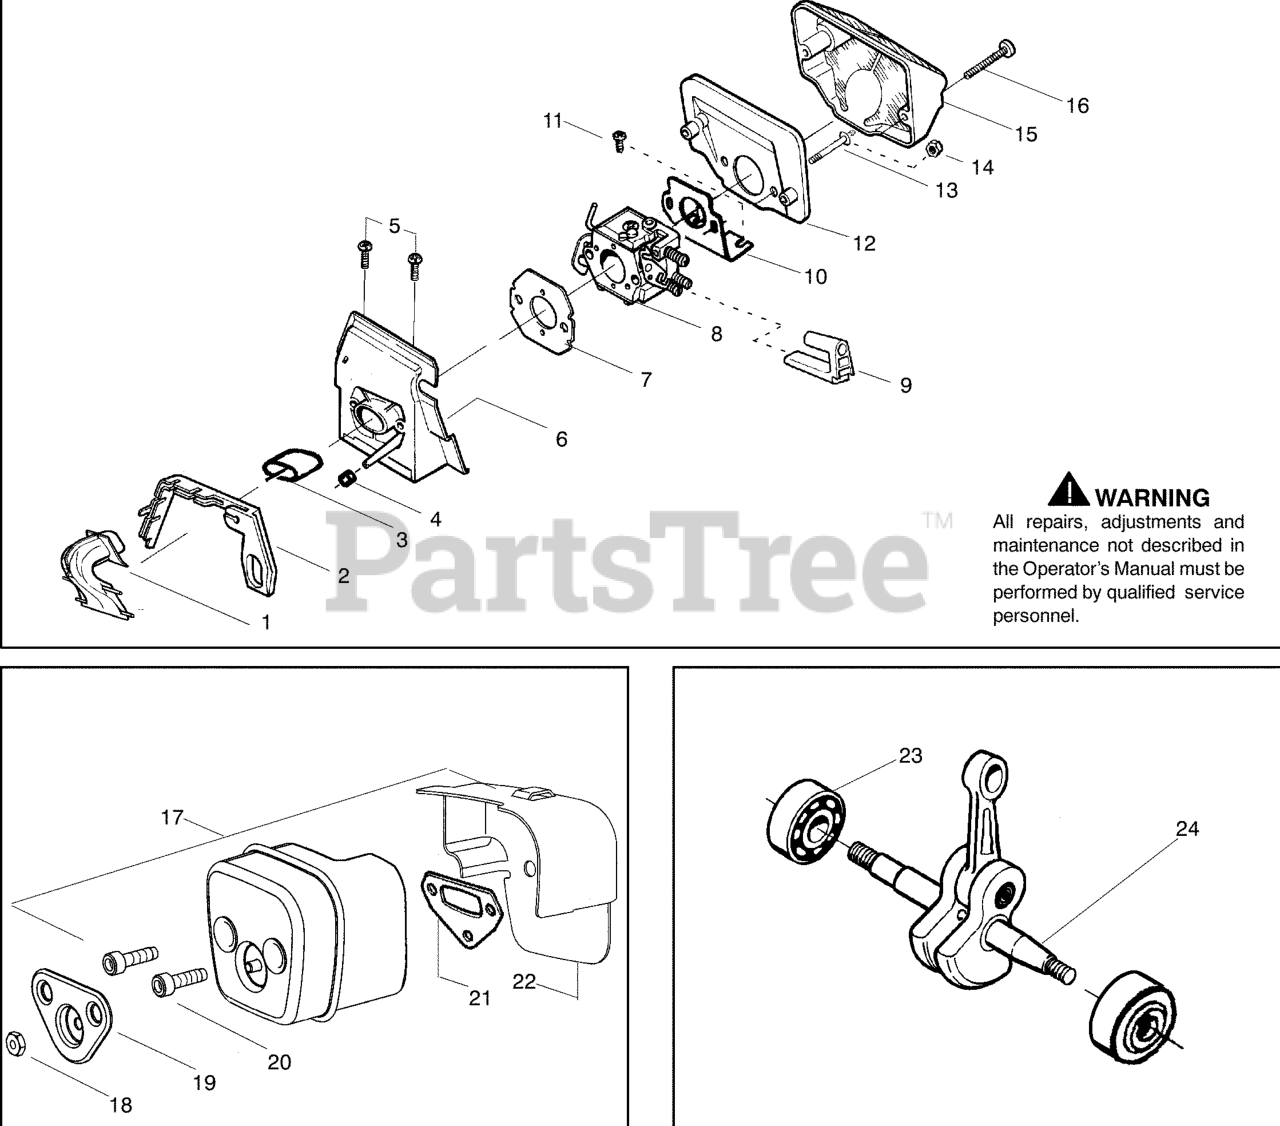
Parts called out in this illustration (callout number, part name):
1	INTAKE HORN
2	TURBO CLEAN SEAL
3	INTAKE PIPE
4	IMPULSE PIPE
6	CARB ADAPTOR
7	GSKT,CARB 36/41
8	Carburetor
12	AIR FILTER (BOTTOM)
13	STUD-CARBURETOR
15	AIR FILTER
17	MUFFLER KIT
18	NUT-BRASS
19	COVER BOLT
20	SCREW MUFFLER
21	GASKET-MUFFLER
22	BACKPLATE, MUFFLER
23	BEARING & SEAL ASSEMBLY
24	CRANKSHAFT ASSY 36/41
